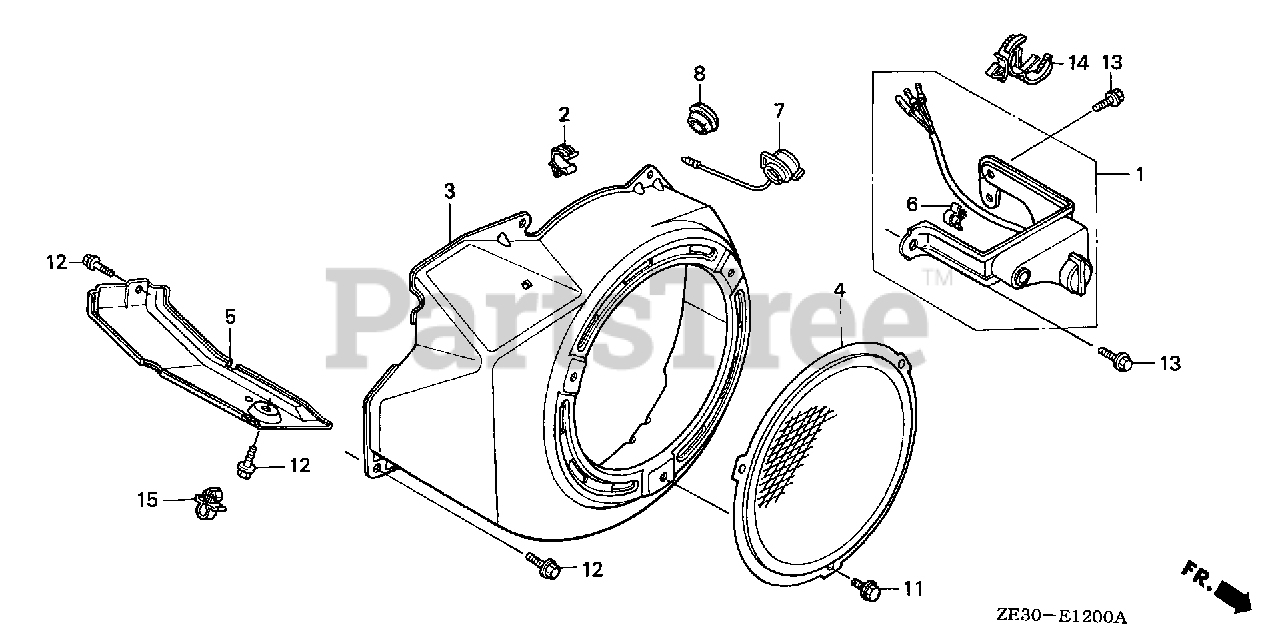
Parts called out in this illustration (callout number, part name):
1	ALERT UNIT, OIL (NOT AVAILABLE)
2	CLIP, TUBE
3	COVER, FAN *R280* (POWER RED)
6	CLIP, IGNITION WIRE (8MM)
7	SWITCH ASSY., ENGINE STOP
12	BOLT, FLANGE (6X12) (CT200)
13	BOLT, FLANGE (6X12) (CT200)
14	CLIP, HARNESS
